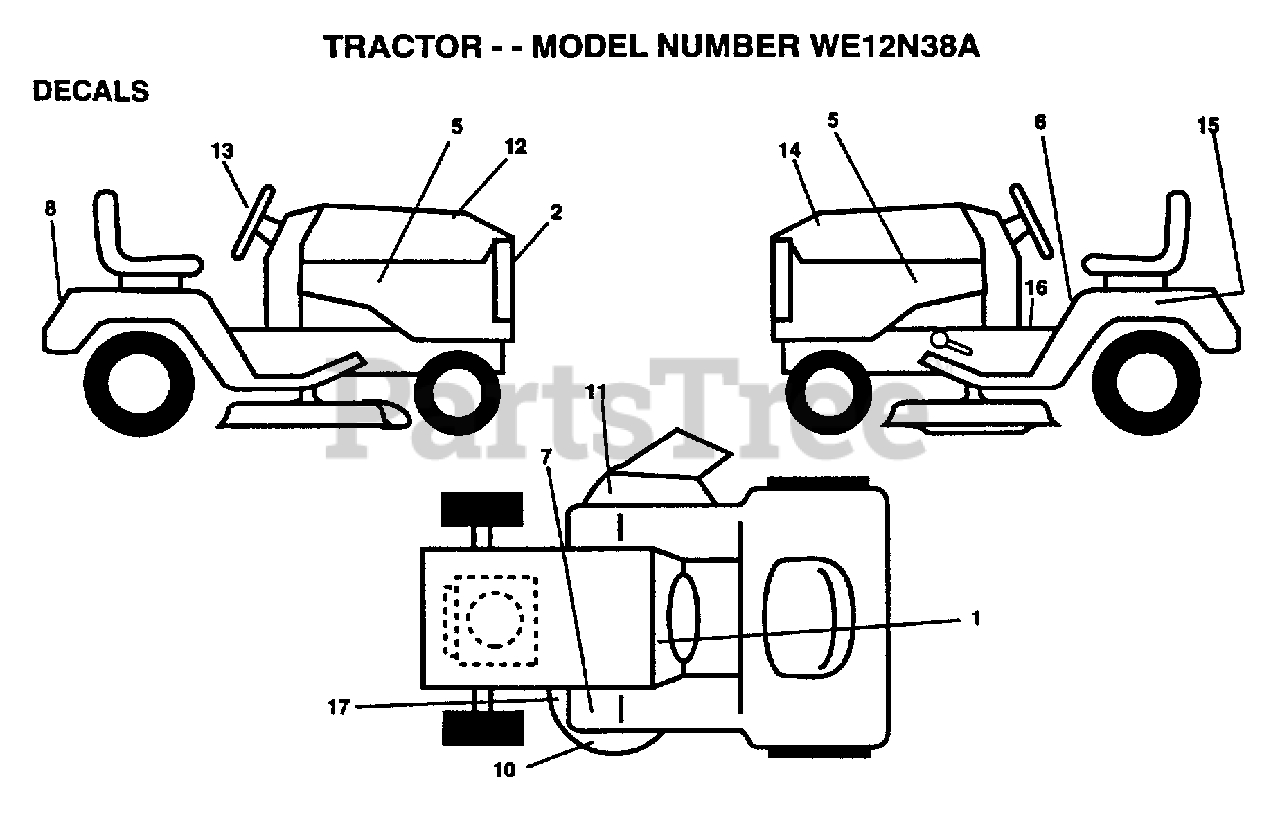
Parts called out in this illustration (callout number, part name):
1	DECAL.DASH.INSTR.
2	DECAL.GRILL
5	DECAL.PNL.SIDE.12
6	DECAL CAUTION
7	DECAL T
8	DECAL.FENDER
10	DECAL.MOWER
11	GUIDE.BELT.MID.SP
12	DECAL.HD.STRIP.RH
13	DECAL.WHL.STRG.
14	DECAL.HD.STRIP.LH
15	DECAL
16	DECAL BRAK PARK
17	DECAL
